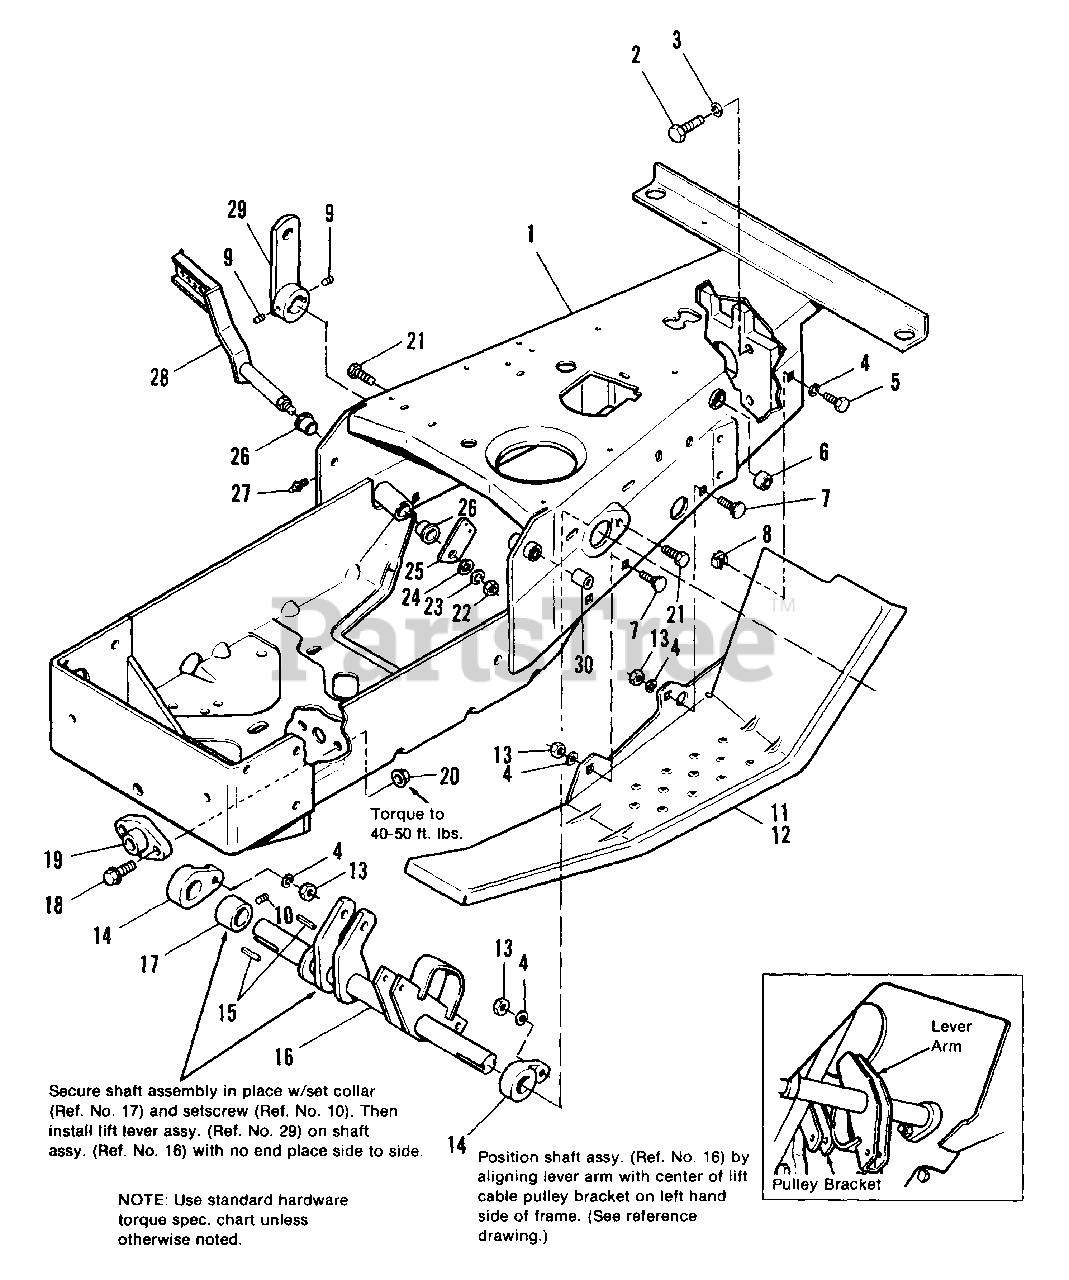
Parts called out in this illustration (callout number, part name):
1	FRAME ASSY., w/Bushings (7114 & 7116 Only)
1	FRAME ASSY., w/Bushings (7117 Only)
2	CAPSCREW, Hex Hd., 7/16-14 x 1-1/2
3	LOCKWASHER, 7/16
4	LOCKWASHER, 5/16
5	CAPSCREW, Hex Hd., 5/16-18 x 3/4
7	BOLT, Carriage, 5/16-18 x 3/4
8	NUT, Speed, 5/16-18
9	SETSCREW, 5/16-18 x 1/4
10	SETSCREW, 5/16-18 x 3/8
11	FOOTREST, LH
12	FOOTREST, RH
13	NUT, Hex, Full, 5/16-18
14	BEARING, Lift Lever
16	SHAFT ASSY., Lift
17	COLLAR, Set
18	SCREW, Hex, Whiz, Flange, 3/8-16 x 1-1/4
19	BEARING, Pivot
20	LOCKNUT, Hex, Flange, 3/8-16
21	CAPSCREW, Hex Hd., 5/16-18 x 1-3/4
22	NUT, Hex, Full, 3/8-16
23	LOCKWASHER, 3/8
24	WASHER, Plain, 3/8
25	ARM, Foot Pedal
27	FITTING, Grease
28	PEDAL ASSY., Foot
29	LEVER ASSY., RH
30	BEARING, Interm. Pinion
